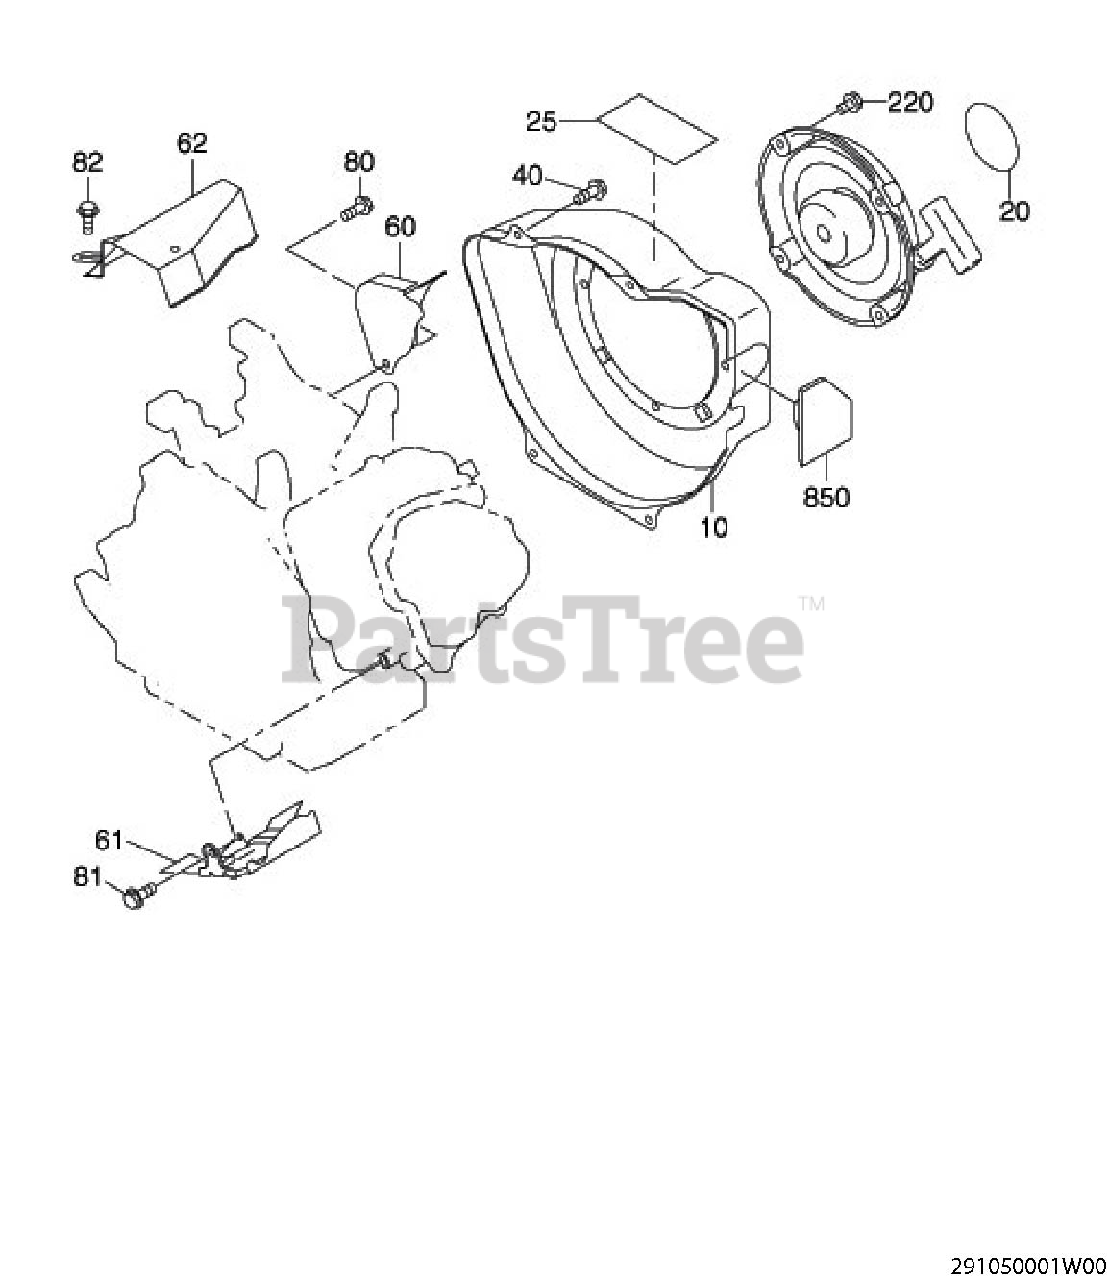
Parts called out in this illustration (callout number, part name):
10	BLOWER HOUSING CP
20	LABEL(TRADE MARK)
25	LABEL(WARNING)
40	FLANGE BOLT
60	BAFFLE 1(CASE) CP
61	BAFFLE 2(HEAD)
62	DUCT (CASE) CP
80	BOLT
81	FLANGE BOLT
82	FLANGE BOLT
220	BOLT AND WASHER AY
